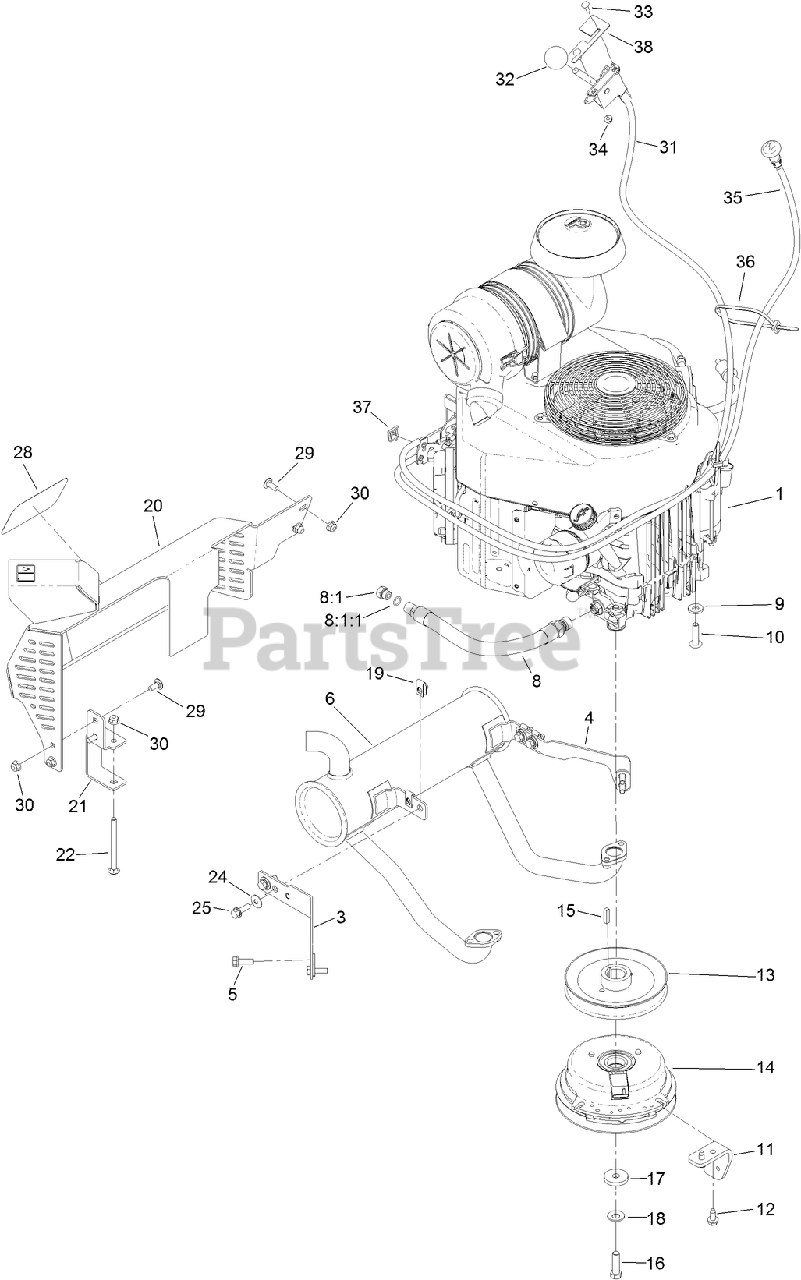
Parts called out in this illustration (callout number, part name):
1	ENGINE-KAWASAKI, FX691V
3	BRACKET-MUFFLER, FRONT
4	BRACKET-MUFFLER, REAR
5	SCREW-HHF
6	MUFFLER
8	ENGINE OIL DRAIN HOSE ASM
8:1	PLUG-HH
8:1:1	O-RING
9	WASHER-BELLEVILLE
10	SCREW-BHTF
11	STOP-CLUTCH
12	SCREW-HWHTF
13	PULLEY
14	CLUTCH-200CMS
16	SCREW-HH
17	WASHER
18	WASHER-SPRING
19	NUT-U
20	MUFFLER GUARD ASM
21	BRACKET-MOUNTING, GUARD
22	SCREW-CARR
24	WASHER-BELLEVILLE
25	SCREW-HHF
28	DECAL
29	SCREW-CARR
30	NUT-HF, NI
31	THROTTLE ASM
32	KNOB-BALL
33	BOLT-CARR
34	NUT-LOCK, FLANGE
35	CABLE-CHOKE
36	TIE-CABLE
37	CLAMP-CABLE
38	PLATE-SET, THROTTLE
